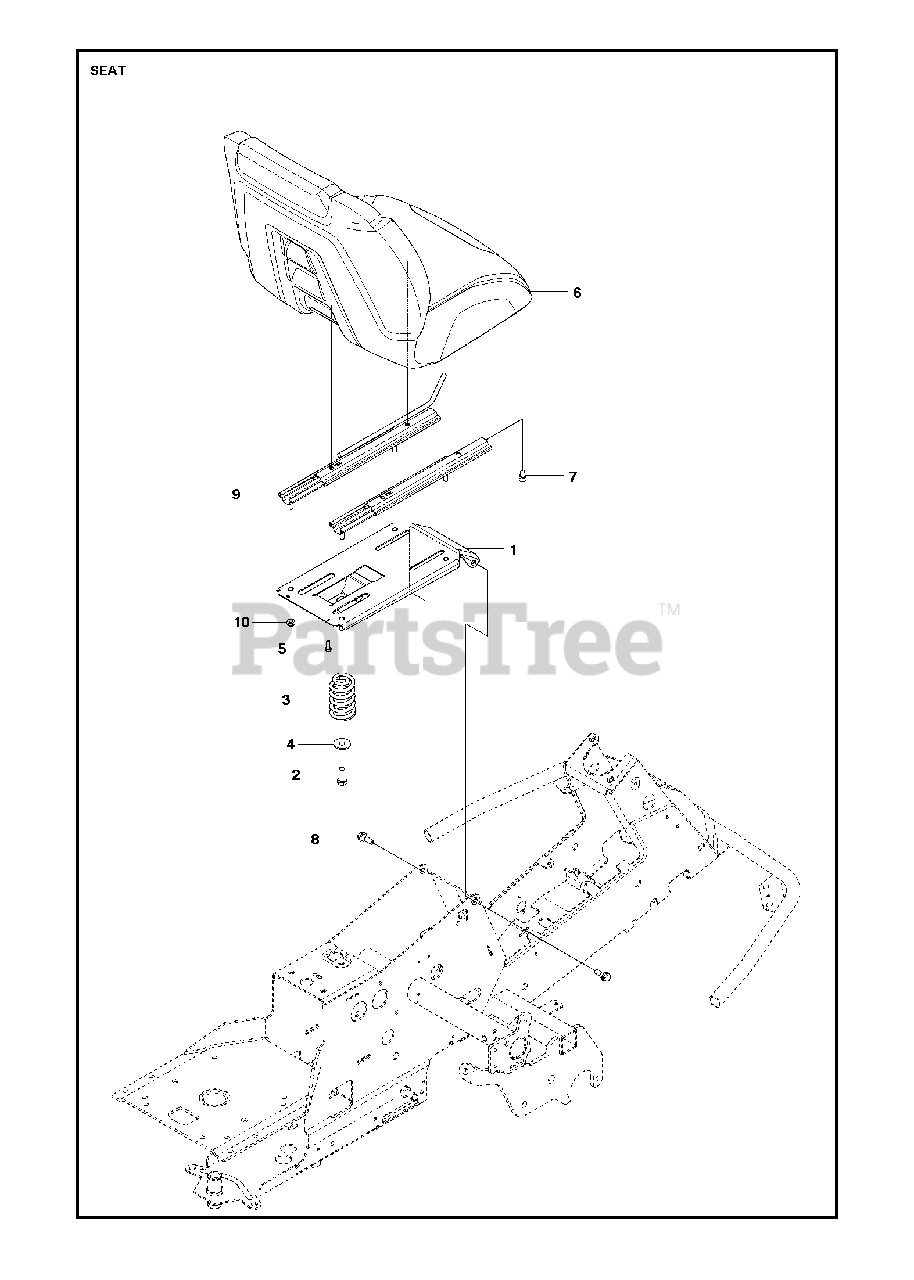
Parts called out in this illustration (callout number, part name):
1	SEAT BRACKET 300 ASSY GREY
2	Screw, M10 X 25
3	SEAT SPRING
5	Screw
6	SEAT HUSQVARNA HIGH BACK
7	Screw, Ihscm
9	SEAT ADJUSTER LEFT & RIGHT
10	LOCKNUT M8
